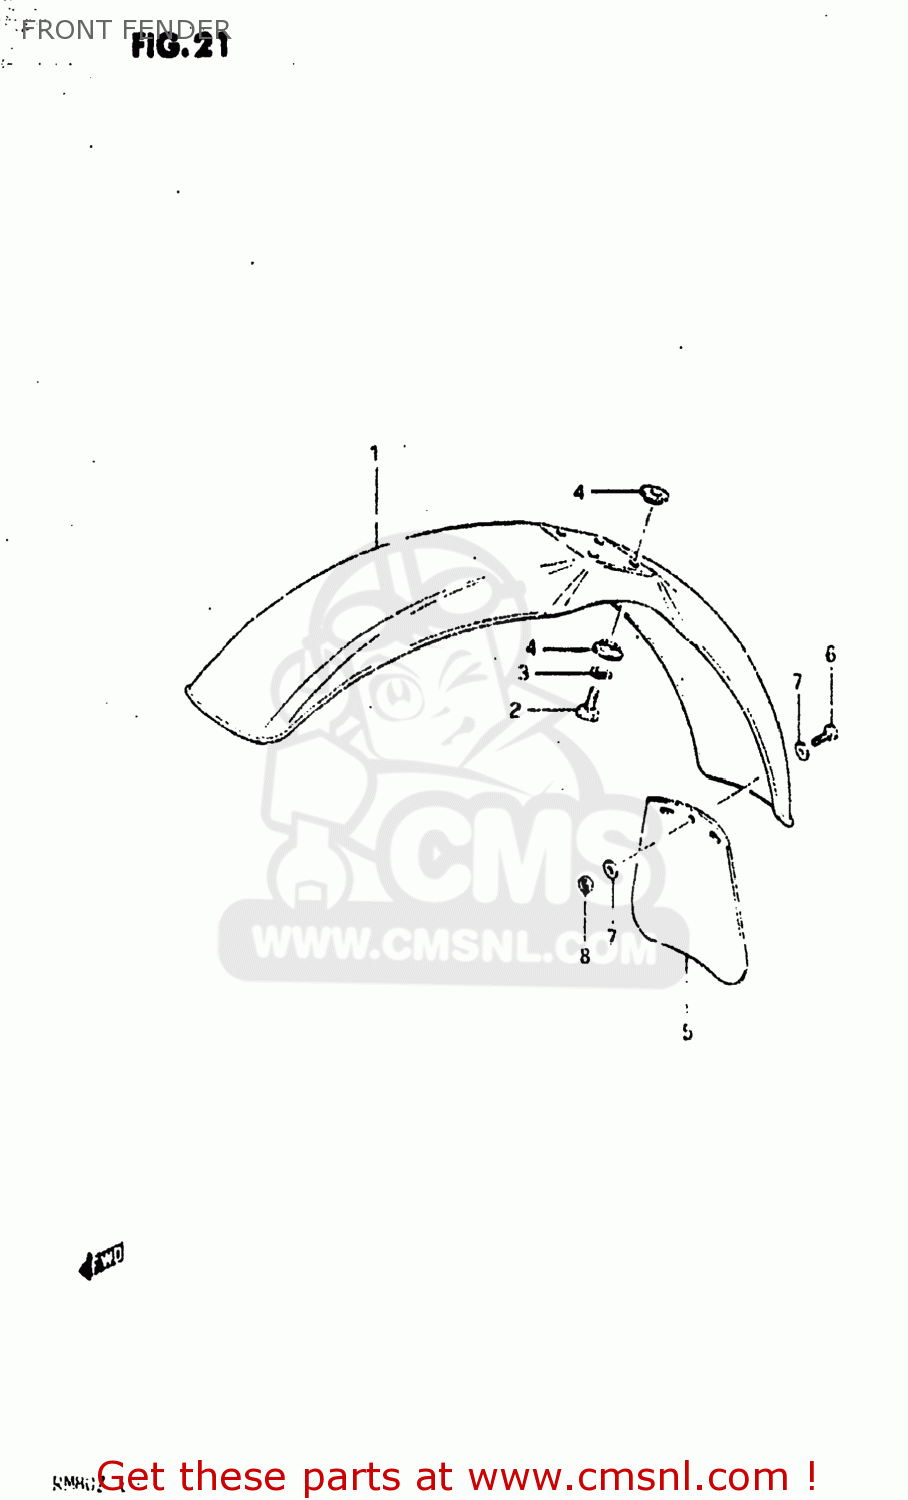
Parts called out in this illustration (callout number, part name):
1	FENDER,FRONT
2	BOLT, UPPER
3	LOCK WASHER
4	SPACER
5	MUD FLAP,FRONT FENDER
6	SCREW
7	WASHER
8	NUT
